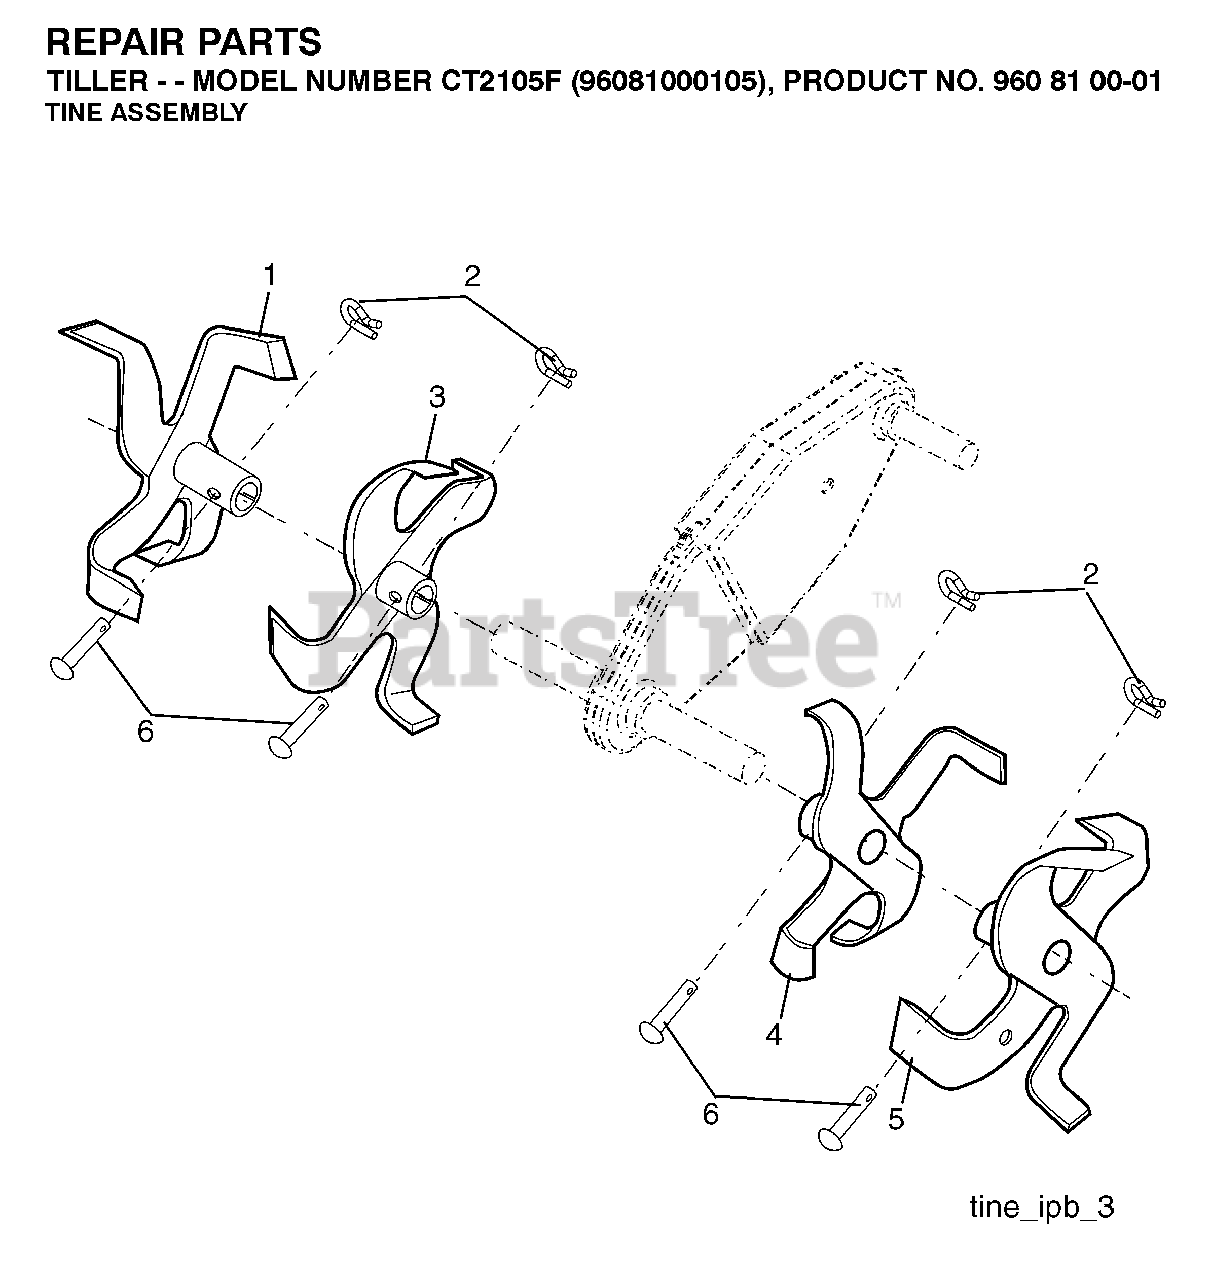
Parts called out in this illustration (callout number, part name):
1	RP TINE
2	SPRING RETAINER
3	RP TINE
4	RP TINE
5	RP TINE
